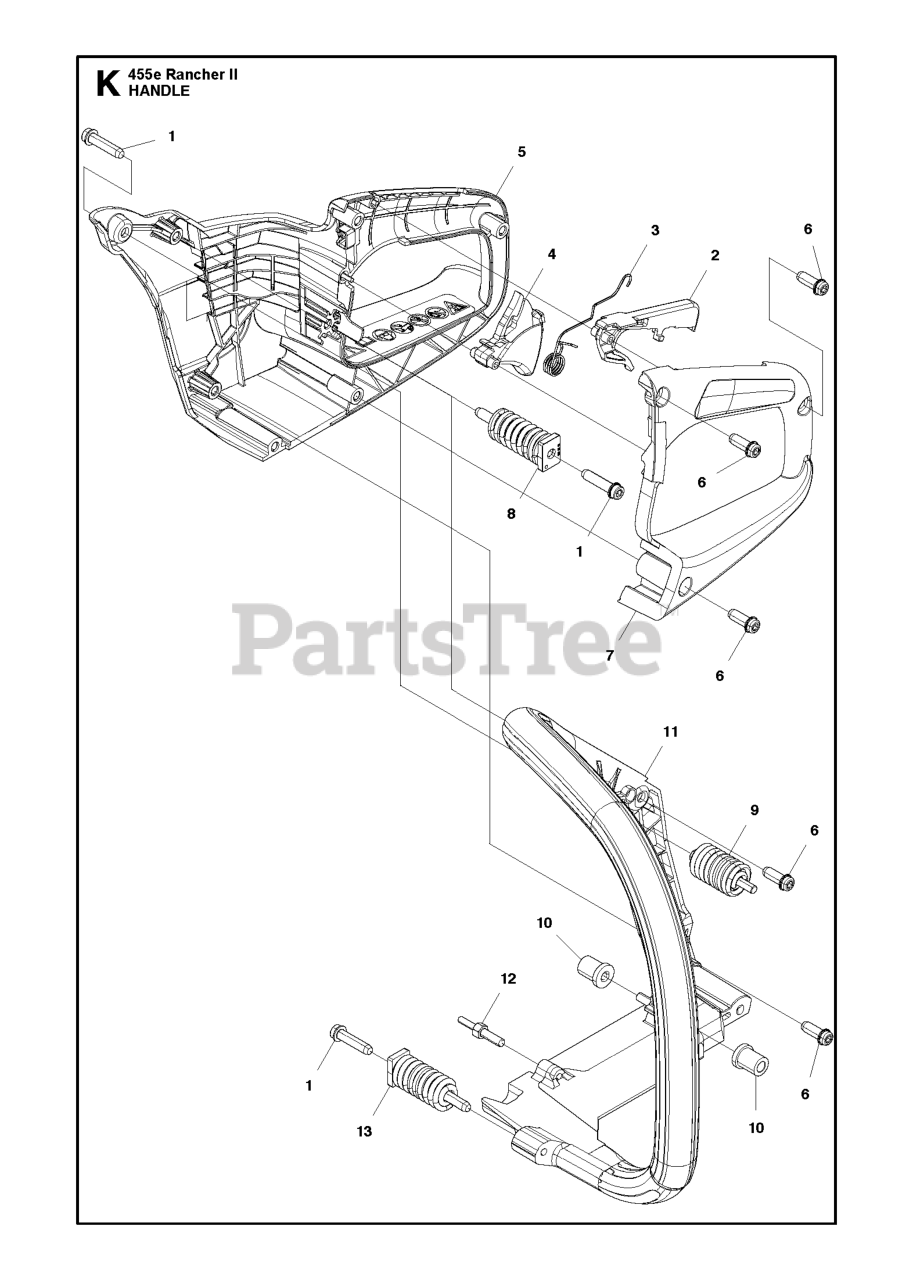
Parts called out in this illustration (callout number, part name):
1	SCREW
2	THROTTLE LOCK
4	THROTTLE TRIGGER
5	REAR HANDLE
7	CAP - LEFT SIDE HANDLE
8	VIBRATION ABSORBER
9	VIBRATIONS ABSORBER
10	MOVEMENT LIMITER
11	FRONT HANDLE
